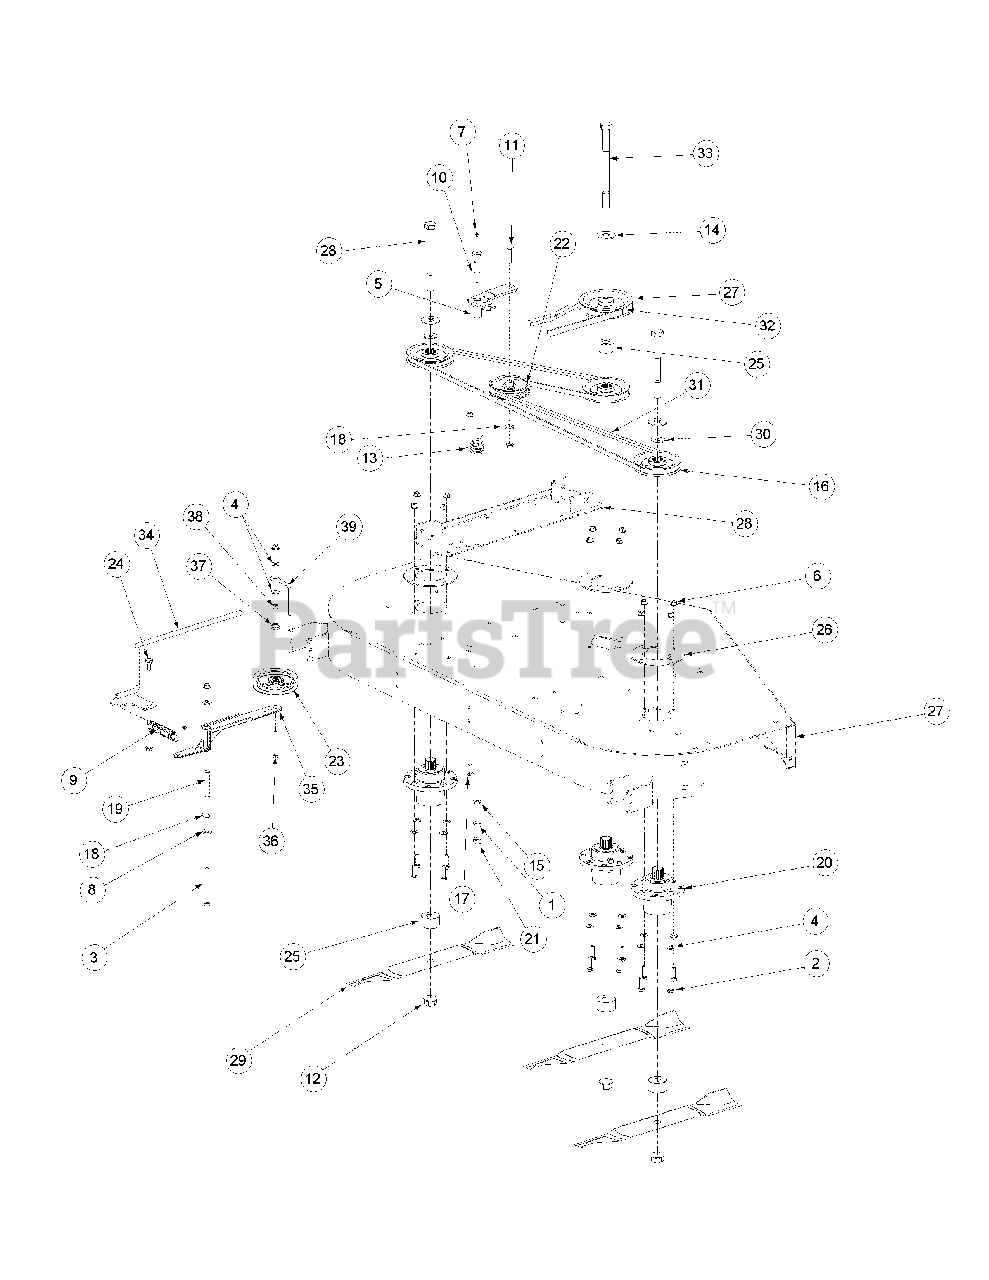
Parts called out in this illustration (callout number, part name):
1	Lock Washer, 7/16
2	Hex Cap Screw, 3/8-16 x 1-1/2
3	Hex Cap Screw, 3/8-16, 4.00
4	Flat Washer, 3/8
5	Idler Arm Casting, Deck Spindle
5	Bearing Sleeve
6	Flange Lock Hex Nut, 3/8-16
7	Grease Fitting, 1/4-28 x 3/16
8	Idler Washer
9	Extension Spring, .98 x OD x 5.000
10	Shoulder Screw, 7/16-14
11	Hex Carriage Screw, 3/8-16, 1.75
12	Flange Hex Nut, 3/4-16
13	Torsion Idler Spring
14	Flat Washer, .781 ID 2.00 OD, .105
15	Flat Washer, .469 ID, .875 OD, .105
16	V-Pulley, 5.00 OD
17	Carriage Bolt, 3/8-16 x 1
18	Flat Washer, .406 ID, 1.0 OD, .105
19	Spacer, .39 ID x .625 OD x 2.75
20	Aluminum Spindle Assembly
21	Hex Nut, 7/16-14
22	Flat Pulley
23	Idler Pulley, 4.06 OD
24	Shoulder Screw, .50 x .27 Lg., 3/8-16
25	Spacer, .760 ID x 2.00 OD x .925
26	Aluminum Spindle Support Plate
27	V-Pulley, Cast, 6.360 OD
28	Hex Cap Screw, 3/4-16, 7.00
29	Hi-Lift Blade, 21.0, 0.756 ID
30	Spacer .812 ID x .218 LG
31	V-Belt, A Section x 122.3
32	V-Belt, B Section x 147.4
33	Hex Cap Screw, 3/4-16, 9.00
34	Spring Tension Rod Assembly
35	Idler Arm Assembly, Flat Top Bearing
36	Hex Cap Screw, 3/8-16 x 2.75
37	Shoulder Spacer, 1.00 x .38 x .38
38	Hex Nut, 3/8-16
39	Belt Guide
